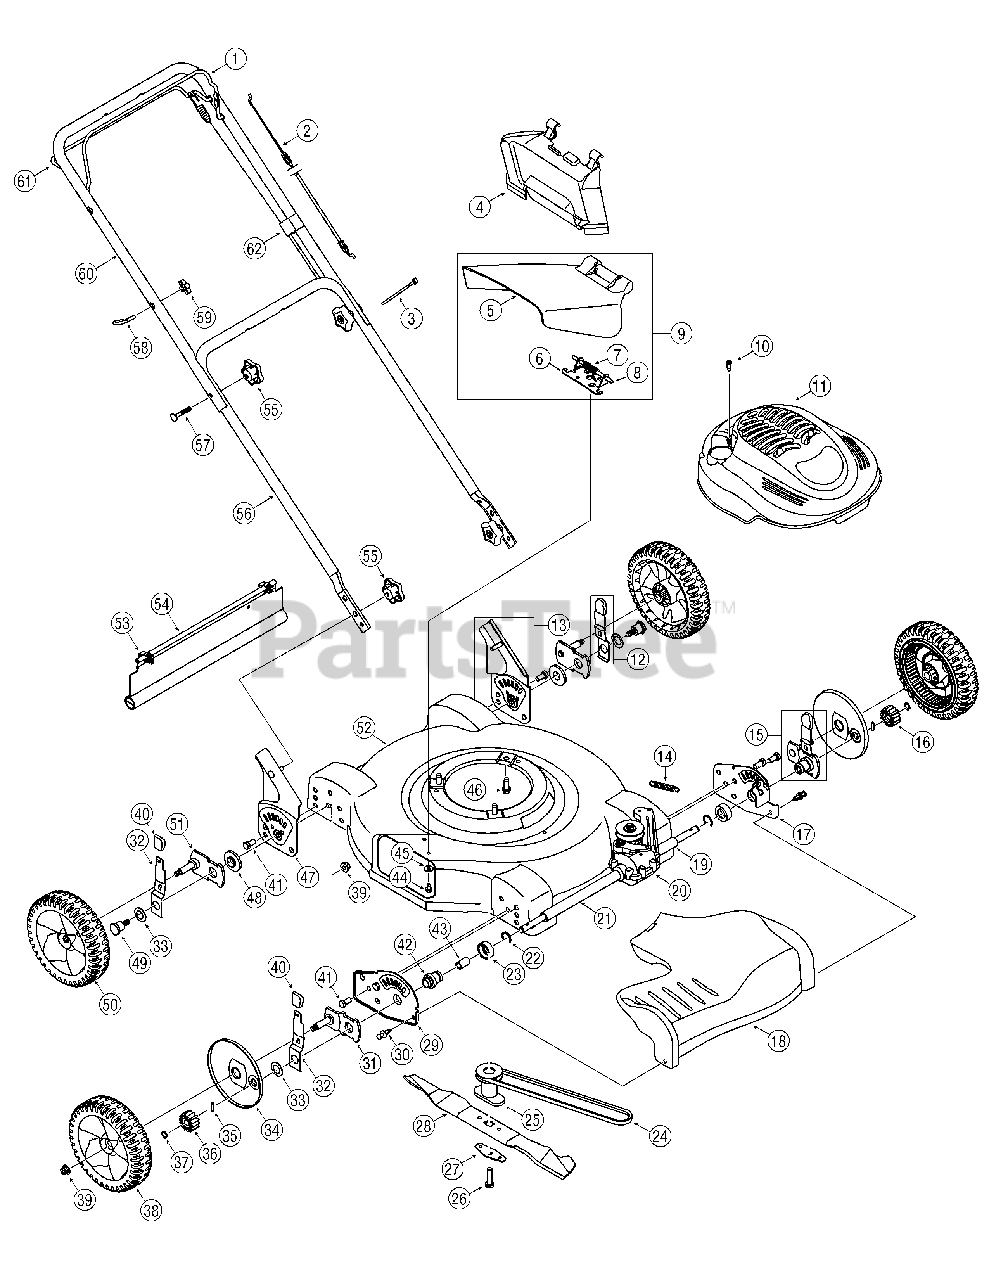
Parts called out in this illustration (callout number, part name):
2	Control Cable 50.56-inch
3	Cable Tie
4	Mulch Plug
5	Side Discharge Chute
6	Chute Deflector Adapter
7	Torsion Spring
8	Hinge Pin
9	Side Discharge Chute Assy
10	Shoulder Screw #10 x .457
11	Engine Shroud
12	Lever Assembly
14	Extension Spring
15	Lever Assembly - Pictured
15	Lever Assembly - Not Pictured
16	Spur Gear - LH
18	Transmission Cover
19	Sleeve Spacer .550 x 2.22
20	Transmission 22-inch
21	Sleeve Spacer .550 x 8.51
22	Retention Ring
23	Bearing Spacer
24	V-Belt
25	Blade Adapter
26	HH Cap Screw 3/8-24 x 1.50
27	Bell Blade Support
28	22-inch Mulching Blade
30	Plastic Rivet
31	Pivot Arm Assembly
32	Spring Lever
33	Bell Washer .760 x 1.25 X .041
34	Wheel Dust Cover
35	Dowel Pin 3/16 x .75
36	Spur Gear - RH
37	Screw 1/4-20 X .39
38	Wheel 8 x 1.8 SPK BAR Fwd
39	Flange Lock Nut 3/8-16
40	Height Adjustment Knob
41	HH Cap Screw 3/8-16 x .75
42	Bearing Support
43	Sleeve Bearing 502 x .627
44	TT Screw 1/4-20 x .500
45	Bell Washer .265 x .75 x .062
46	TT Screw 3/8-16 x 1
49	Shoulder Screw .75 x .625
50	Wheel 8 x 1.8 SPOKE Bar
51	Pivot Arm Assembly
53	Hinge Clip
54	Trailshield
55	Star Knob
57	Carriage Bolt 5/16-18 x 2
58	Eye Bolt
59	Handle Knob
61	Drive Control
